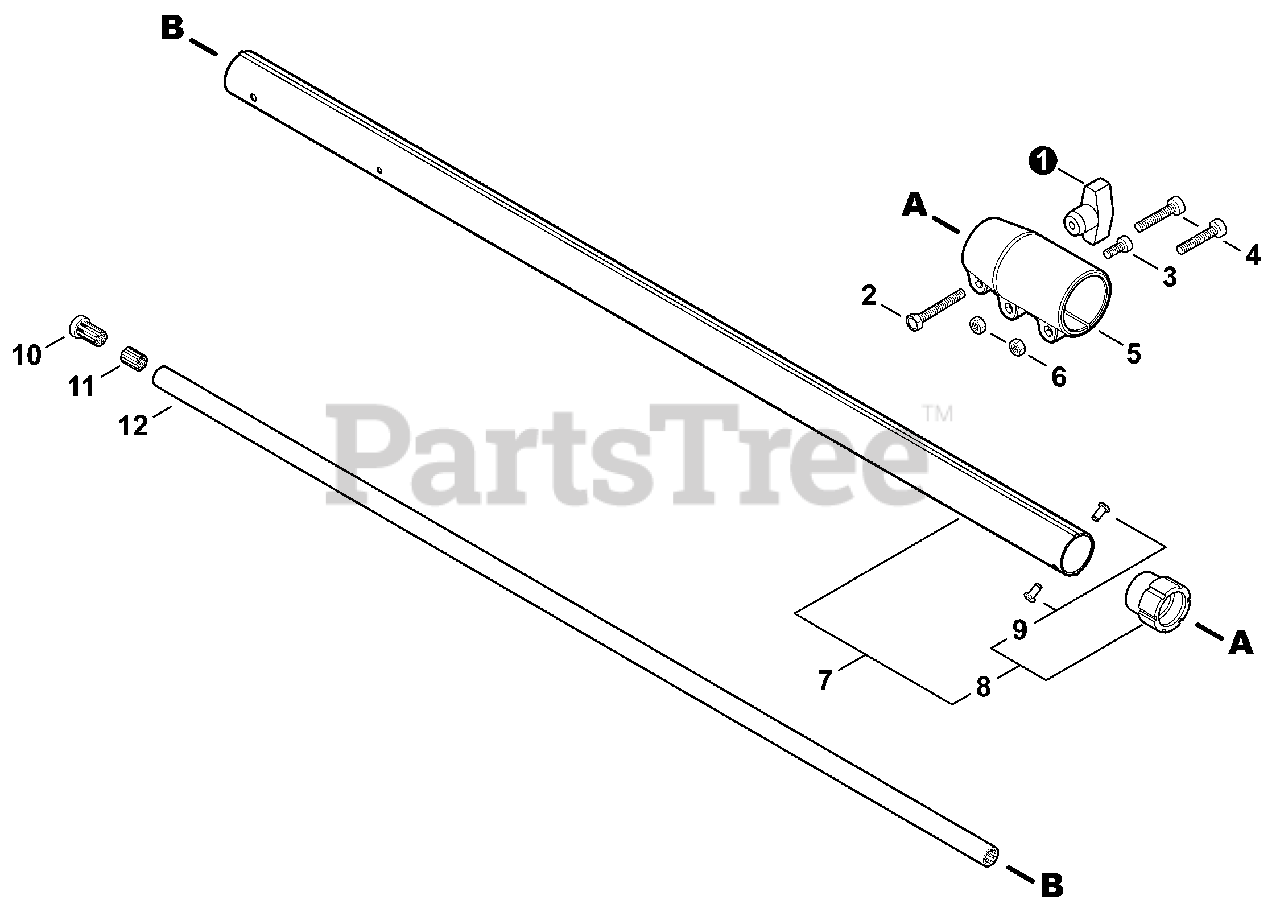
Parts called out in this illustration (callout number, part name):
1	THUMBSCREW
2	BOLT 6×25
3	BOLT 5×12
4	BOLT 5×20
5	COUPLING
6	NUT M5
7	MAIN PIPE ASSY - BLACK
8	HOLDER ASSY, BEARING
10	SOCKET - OUTER
11	SOCKET - INNER
12	DRIVESHAFT - UPPER
